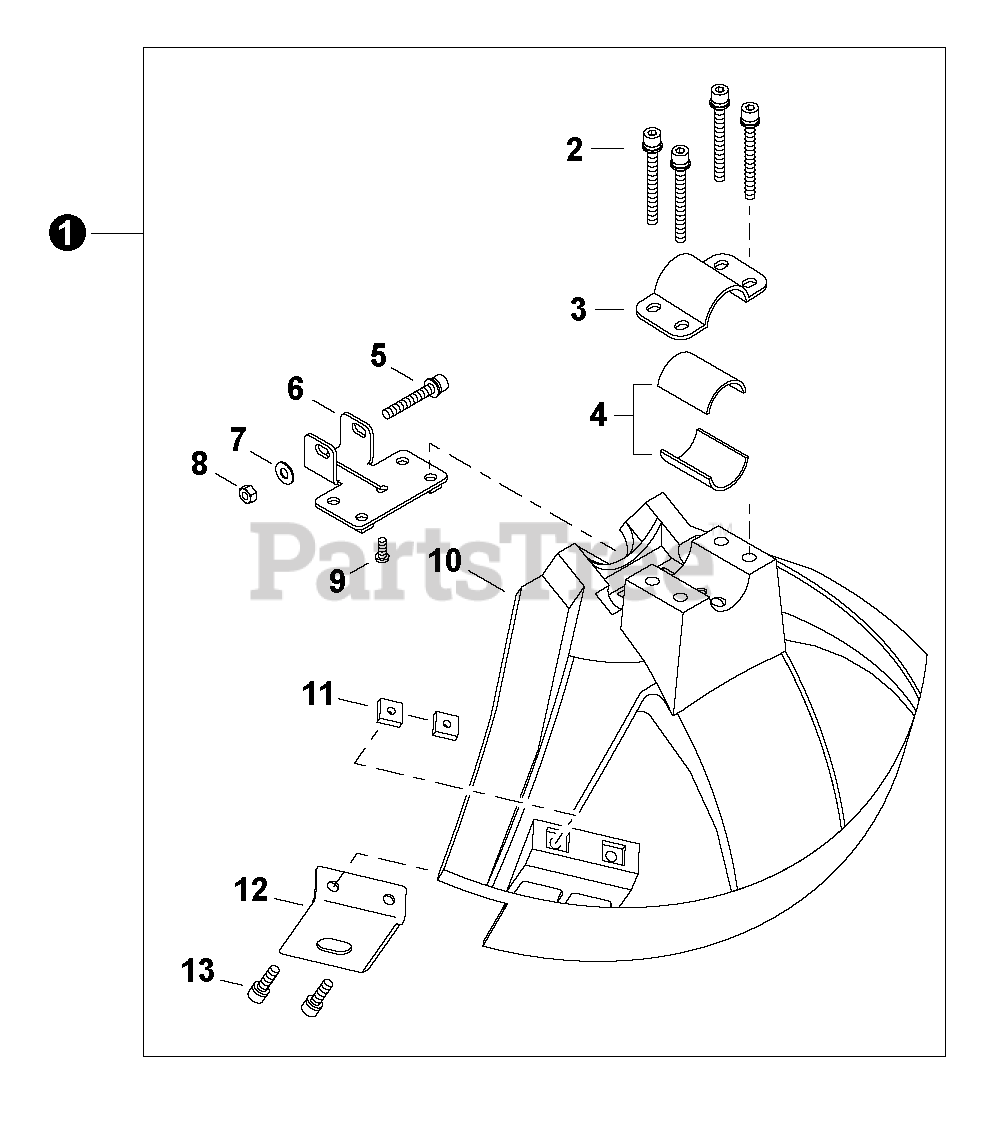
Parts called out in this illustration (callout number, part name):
1	Debris Shield Assy
2	Bolt M5x45
3	Clamp, Upper
4	Spacer 26
5	Bolt M6x40
6	Plate, Shield Mounting
7	Washer 6
8	Nut, Hex M6
9	Screw Hilo 4x10
10	Shield, Debris
13	Bolt M5x16
